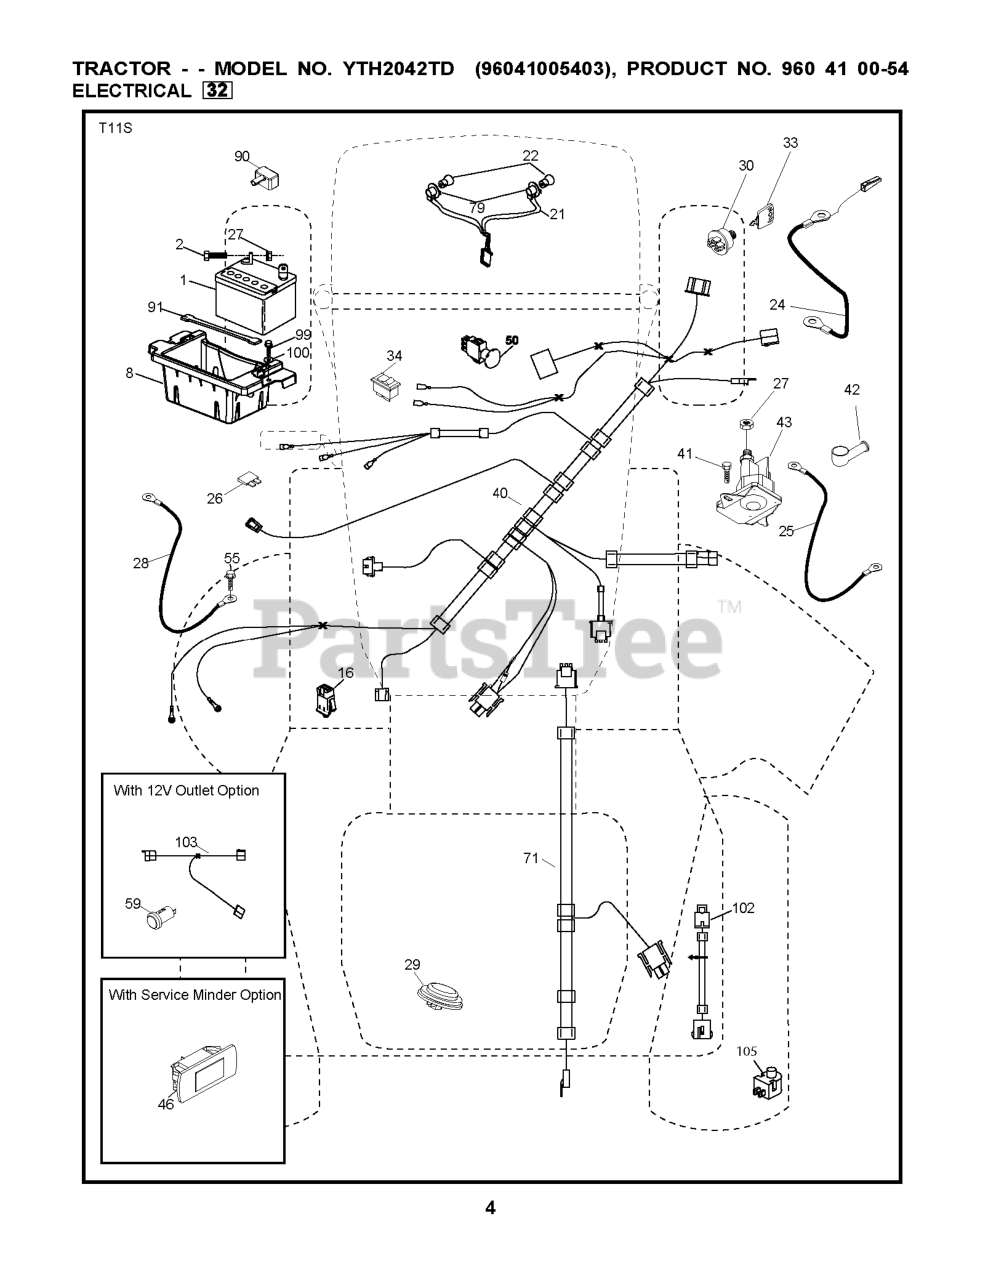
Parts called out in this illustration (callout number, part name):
1	Battery 12 Volt 25 Amp
2	BOLT.HEX.1/4.X.3/4.DICHROMATE
8	BOX.BATTERY.MOUNT.FRONT.LT
16	SWITCH INTERLOOK PUSH-IN
21	HARNESS ASSY LIGHT
24	CABLE.BATT.POS.WIRE.TG.DA SOL
25	CABLE.STARTER.6G.BL/RED.17.5
26	FUSE 20AMP
27	NUT
28	CABLE GROUND 6 GA 21" 90T BLK
29	SWITCH.SEAT.DELTA.OPC.
30	SWITCH.IGN.DELTA.W.LGH.ROS
33	KEY.CHAIN.BLISTER.PACK.GEN.USA
40	HARNESS.IGN.DASH.HUQ/P
41	SCREW
42	TERMINAL COVER
43	SOLENOID.W/BRASS.PLUNGER
46	RP.GUAGE.SRVCMNDR.HRMTR.
50	RP.PTO.SWITCH.8 TERMINAL.BLACK
55	SCREW 5/16"
59	OUTLET.12-VOLT
71	HARNESS-CHASSIS SUB
79	BULB HOLDER ASM.
90	COVER.TERMINAL.BATTERY
91	STRAP.BATTERY.MOUNT.FRONT(2 2)
99	SCREW HEXWSHR 1/4-20X3/4
102	HARNESS PIGTAIL PCH TEX ROS
103	HARNESS PIGTAIL 12V OUTLET
105	REVERSE SWITCH
